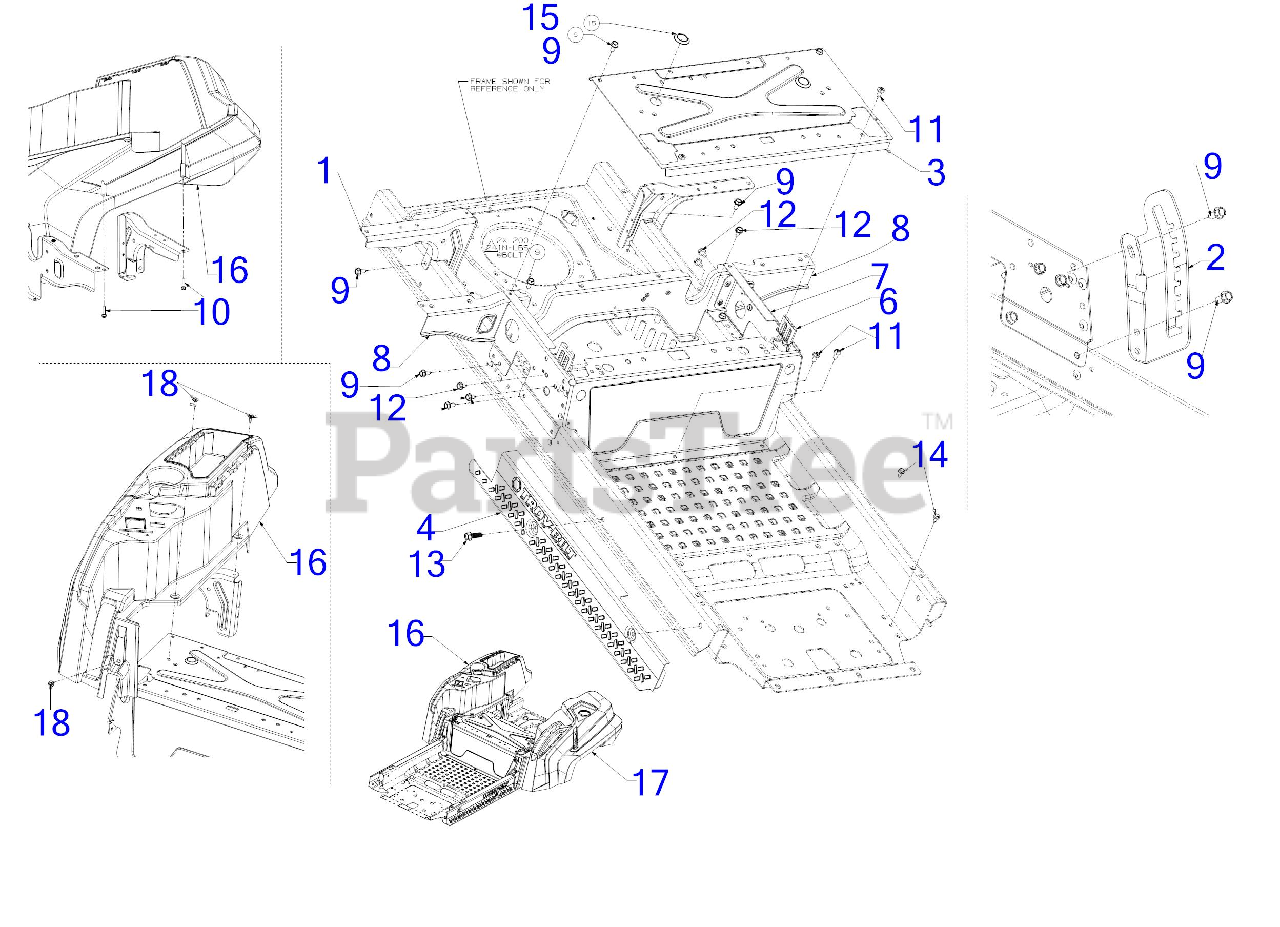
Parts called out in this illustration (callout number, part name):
2	HEIGHT INDEX BRACKET
9	SCREW 5/16-18 x .750
10	SCREW 5/16-14 x 1
11	SCREW 5/16-18 x .750
12	SCREW 5/16-18 x .500
13	SCREW 3/8-16 X1.250
14	SCREW 1/4-20X.625
16	CONSOLE (RH)
17	CONSOLE (LH)
18	SHOULDER SCREW M6-1 .368 X.115
